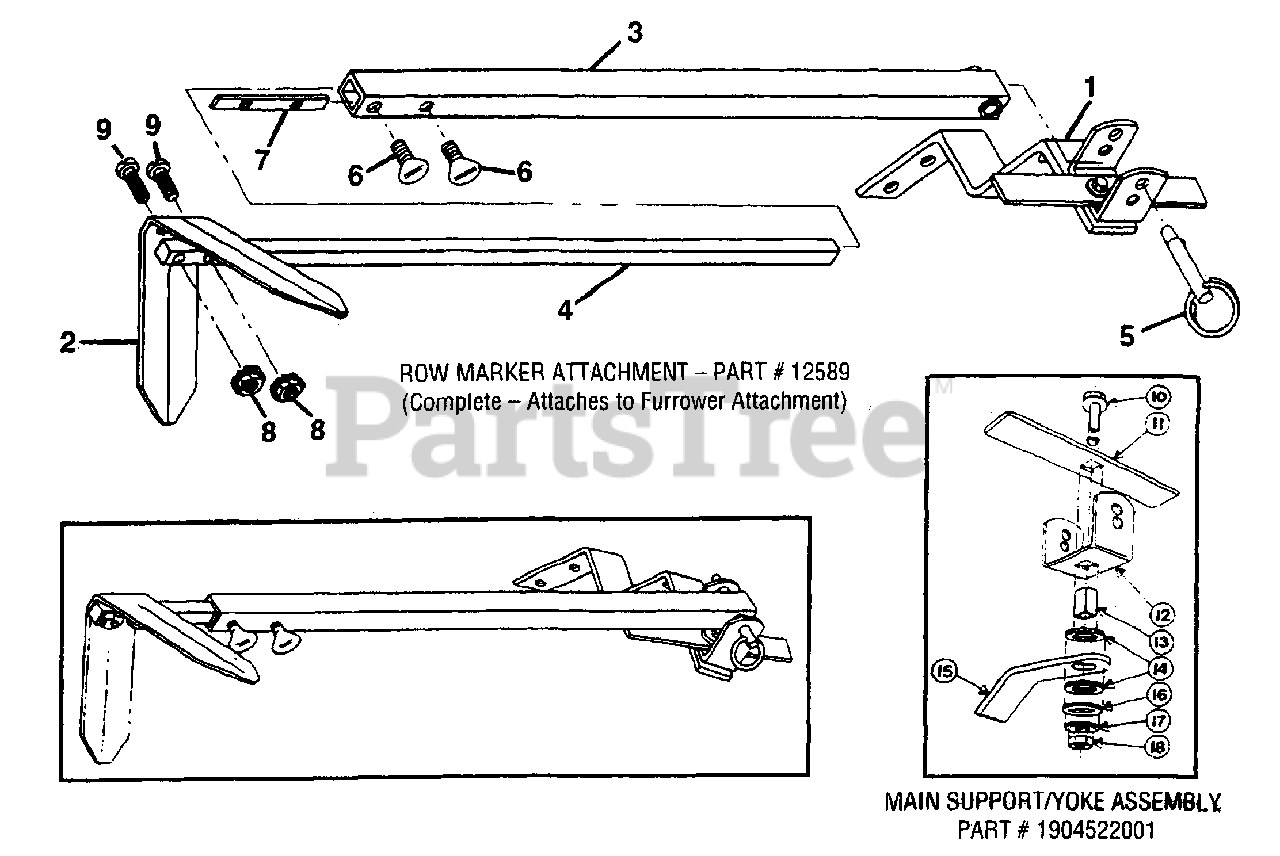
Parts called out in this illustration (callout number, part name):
1	Complete Main Support & Yoke Assy.
2	Marker Blade
3	Marker Arm
4	Marker Extension Arm
5	Hitch Pin
6	Thumbscrew, 1/4-20 x 1/2
7	Nut Bar
8	Hex Nut, #10-24 w/attached start washers
9	Round Hd. Screw, #10-24 x 1
10	Hex Flange Screw, 3/8-16 x 1-1/2'
11	Stop Bar
12	Yoke
13	Tube Key (square)
14	Friction Washer
15	Main Support
16	Washer (square hole)
17	Disc Spring Washer
18	Hex Nut, 3/8-16
